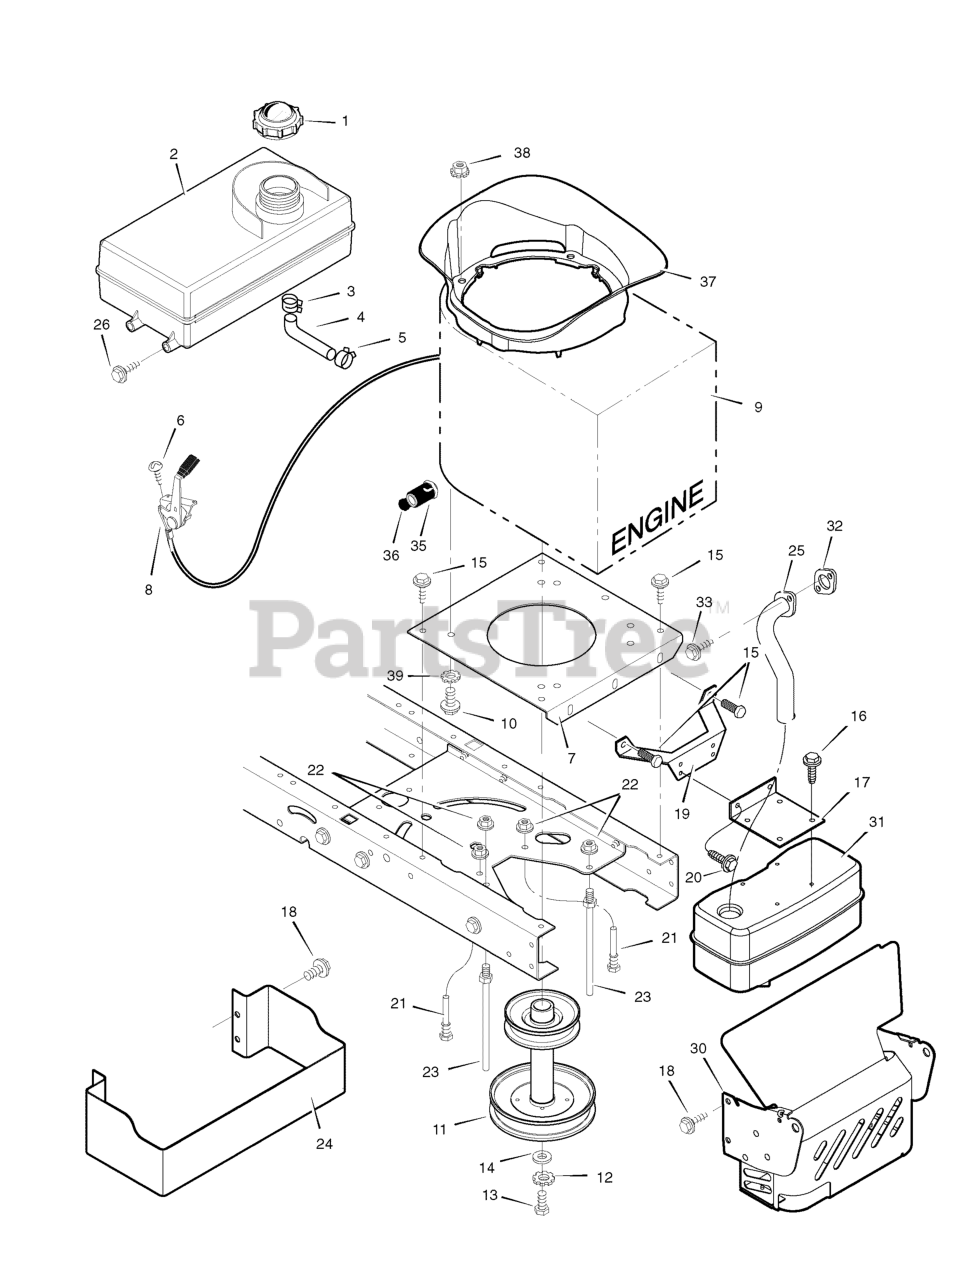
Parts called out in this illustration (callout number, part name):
1	Fuel Cap
2	TANK, Fuel 1.4 Gal.
3	Hose Clamp
4	Fuel Line (Must cut to length)
5	Hose Clamp
7	Plate, Engine
8	Throttle Control
9	Engine, Briggs & Stratton - INTEK *
10	Bolt, Engine Mount
11	STACK PULLEY ASSEMBLY
12	Lockwasher
13	Bolt, Hex
17	Bracket, Muffler
19	Bracket, Muffler Mount
21	Guide, Belt
22	Nut, Flange
23	Guide, Belt
24	GUARD, Heat Shield
25	Exhaust Tube, Single
30	Shield, Heat
31	Muffler
32	GASKET, Exhaust
35	Valve, Oil Drain
36	Cap, Oil Drain
38	Nut, Keps 1/4--20
39	Washer, Star 3/8-0.68 x 0.03
